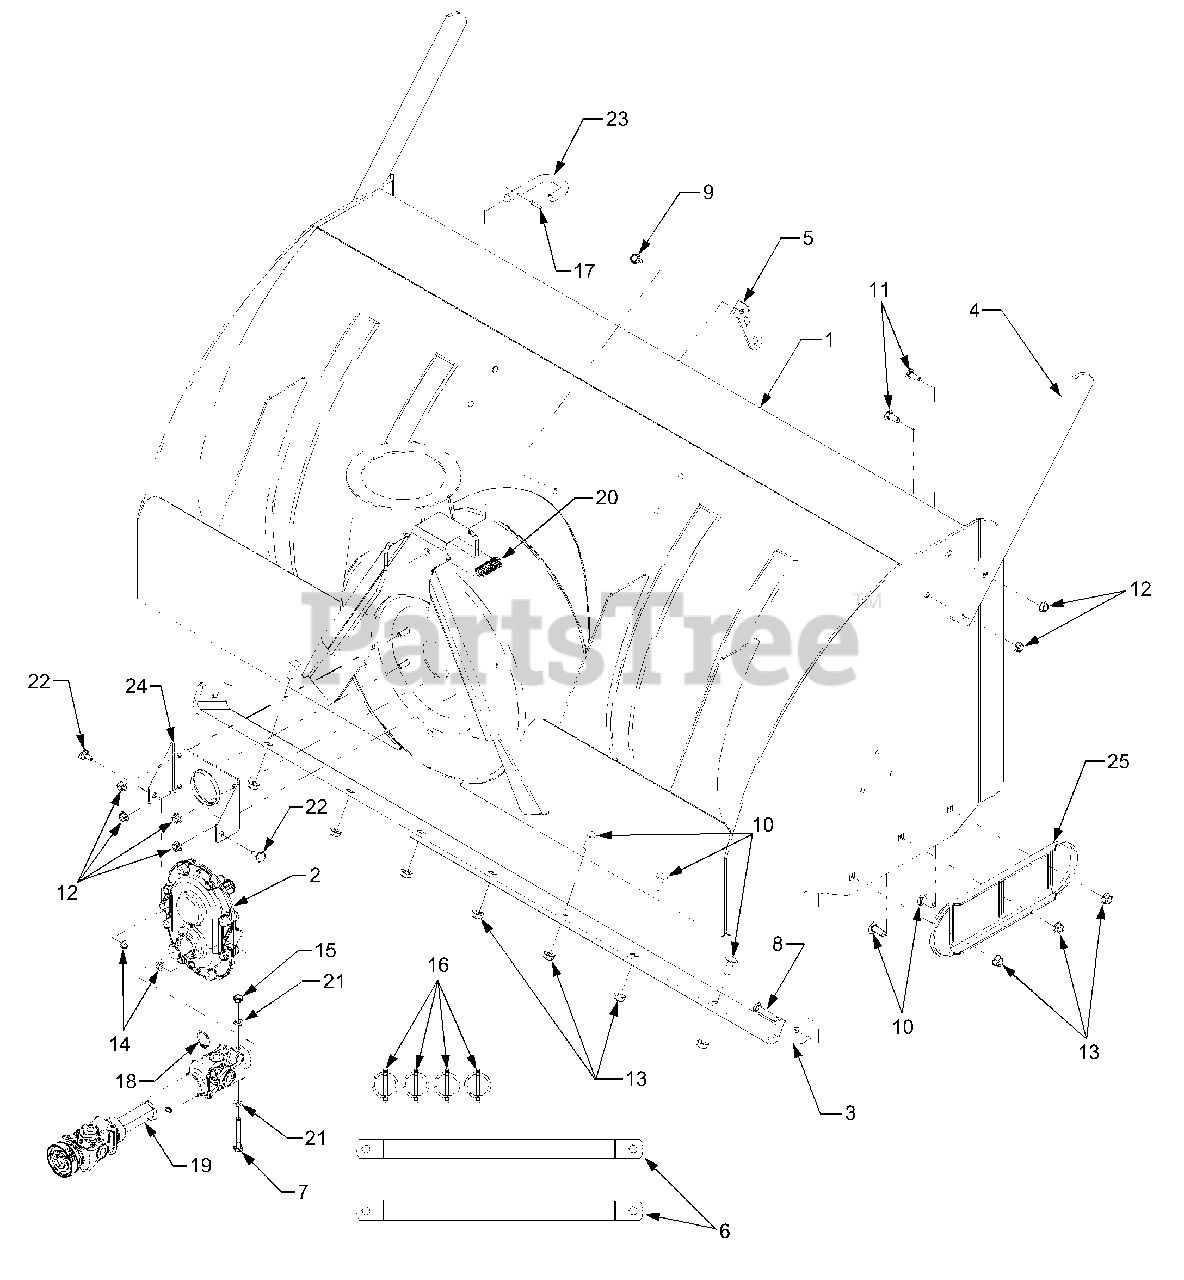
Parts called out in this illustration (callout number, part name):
1	Housing, Spiral
2	Gear Box Assembly
5	Bracket, Gear Box Support
6	Brace, Angle Cylinder Lockout
7	Shear Bolt, 5/16-18 x 2.25 Grade 2
8	Screw, Carriage, 3/8-16 x 1.75
9	Screw, Hex Wash. Hd. Tapp 5/16-12 x .75
10	Screw, Carriage, 3/8-16 x 1.0
11	Bolt, Carriage, 5/16-18 x 7/8
12	Nut, Hex Flange Lock, 5/16-18
13	Nut, Hex Flange Lock, 3/8-16
14	Nut, Hex Flange Lock, 1/4-20
15	Nut, Hex Lock, 5/16-18
16	Pin, Klik
17	Pin, Spirol Spring HD
18	Ring, Snap, for 1.0 Dia.
19	Shaft Assembly, PTO Drive
20	Spring, Compression
21	Washer, Spring, .317 x .625
22	Screw, Shoulder, .375 Dia x .181
23	Pin, Hitch
24	Bracket, Torque
25	Shoe, Skid
